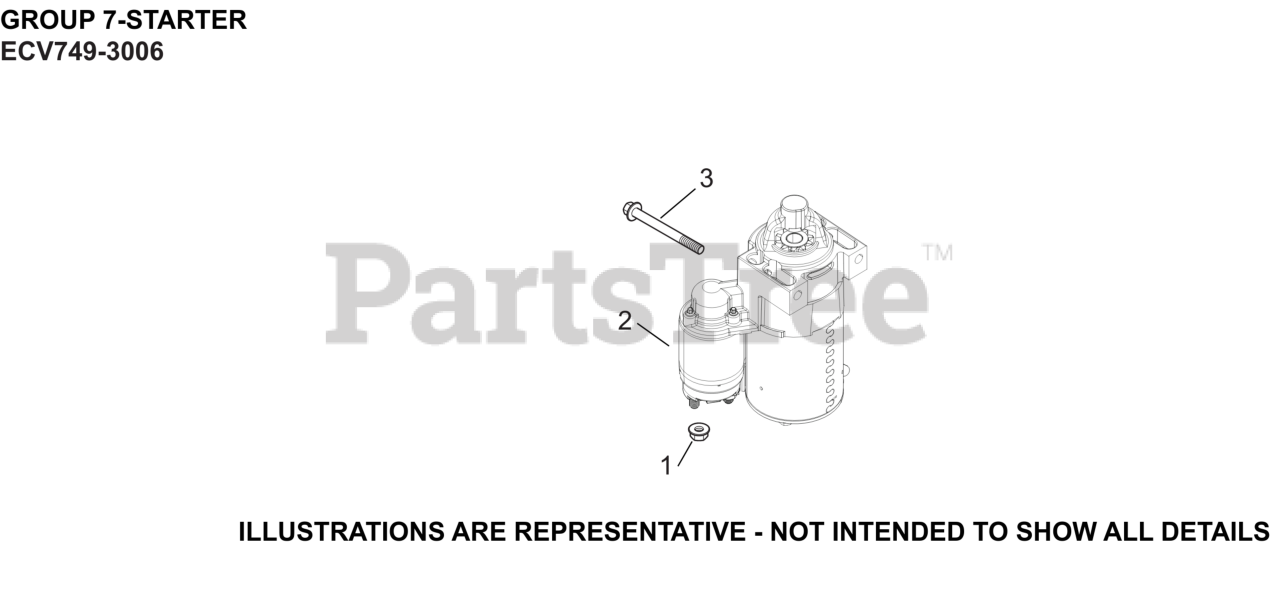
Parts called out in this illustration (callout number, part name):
1	NUT, FLG M8X1.25
2	STARTER, SOLENOID SHIFT (25 098 09-S)
3	SCREW, FLG M8X1.25X80
